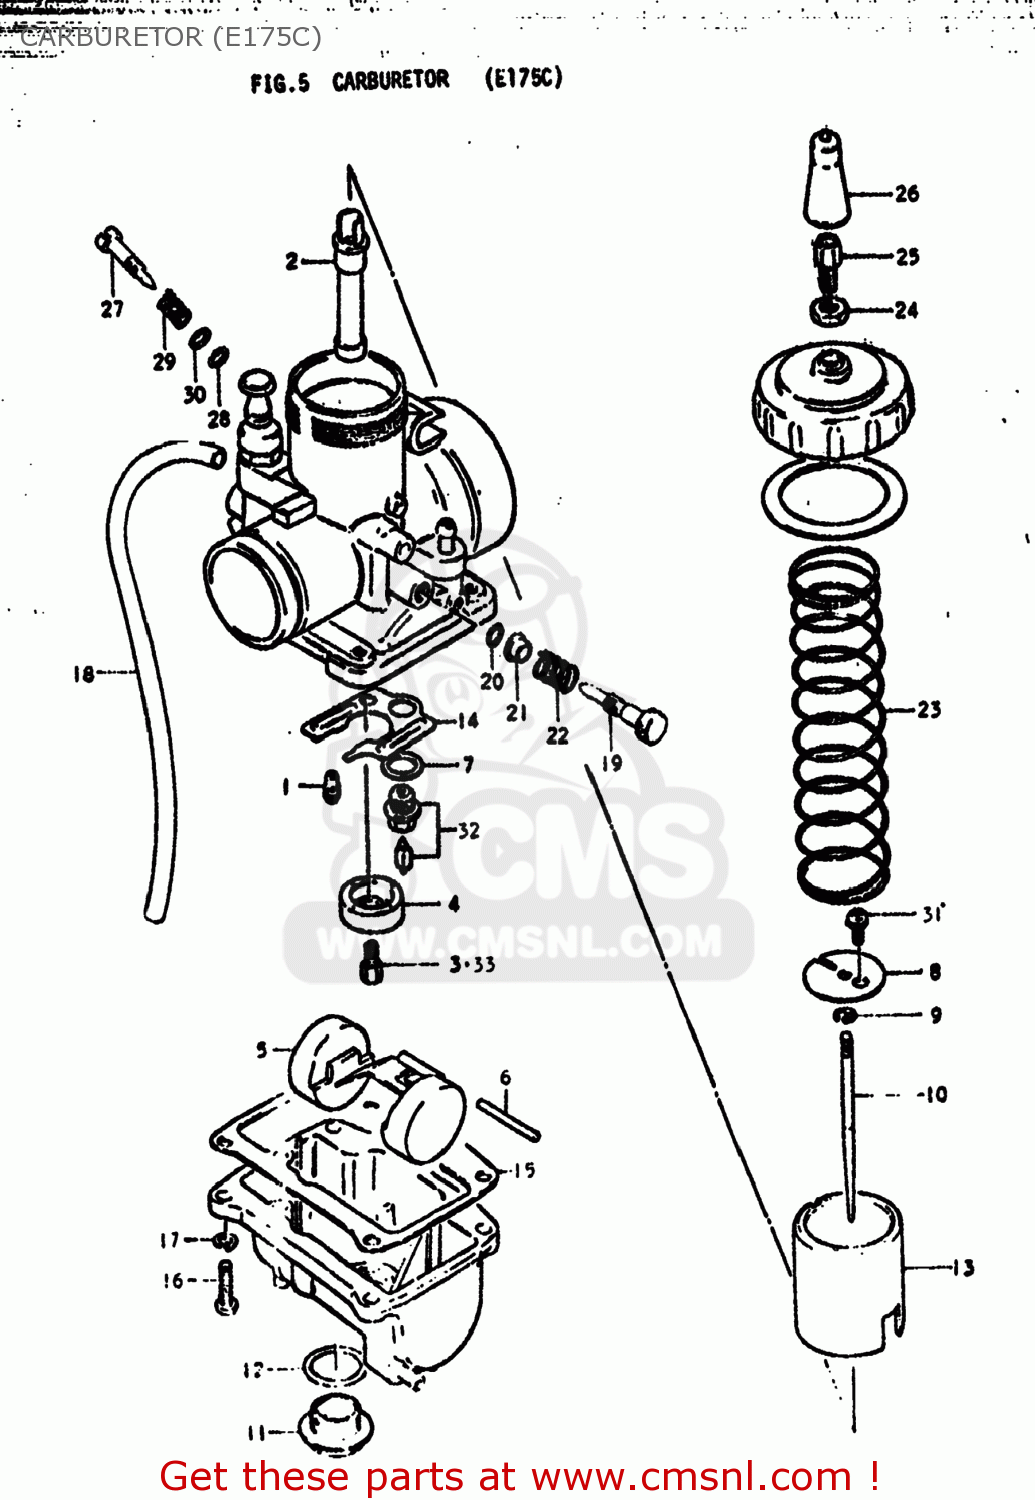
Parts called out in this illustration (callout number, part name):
1	JET
2	JET,NEEDLE
3	JET
4	RING
5	FLOAT
6	PIN,FLOAT
7	GASKET,MAIN JET HOLDER (NAS)
8	PLATE,THROTTLE VALVE
9	CLIP
10	NEEDLE JET
11	SCREW,GUIDE
12	O RING,DRAIN PLUG
13	VALVE,THROTTLE
14	PLATE
15	GASKET,FLOAT CAHMBER (NAS)
16	SCREW
17	LOCK WASHER
18	HOSE
19	ADJUSTER
20	O-RING
21	COVER
22	SPRING,THROTTLE STOP
23	SPRING
24	NUT
25	ADJUSTER,CABLE
26	CAP
27	SCREW,PILOT AIR
28	O RING
29	SPRING
30	WASHER,PILOT AIR SCREW
31	SCREW
32	VALVE ASSY,NEEDLE
33	JET
